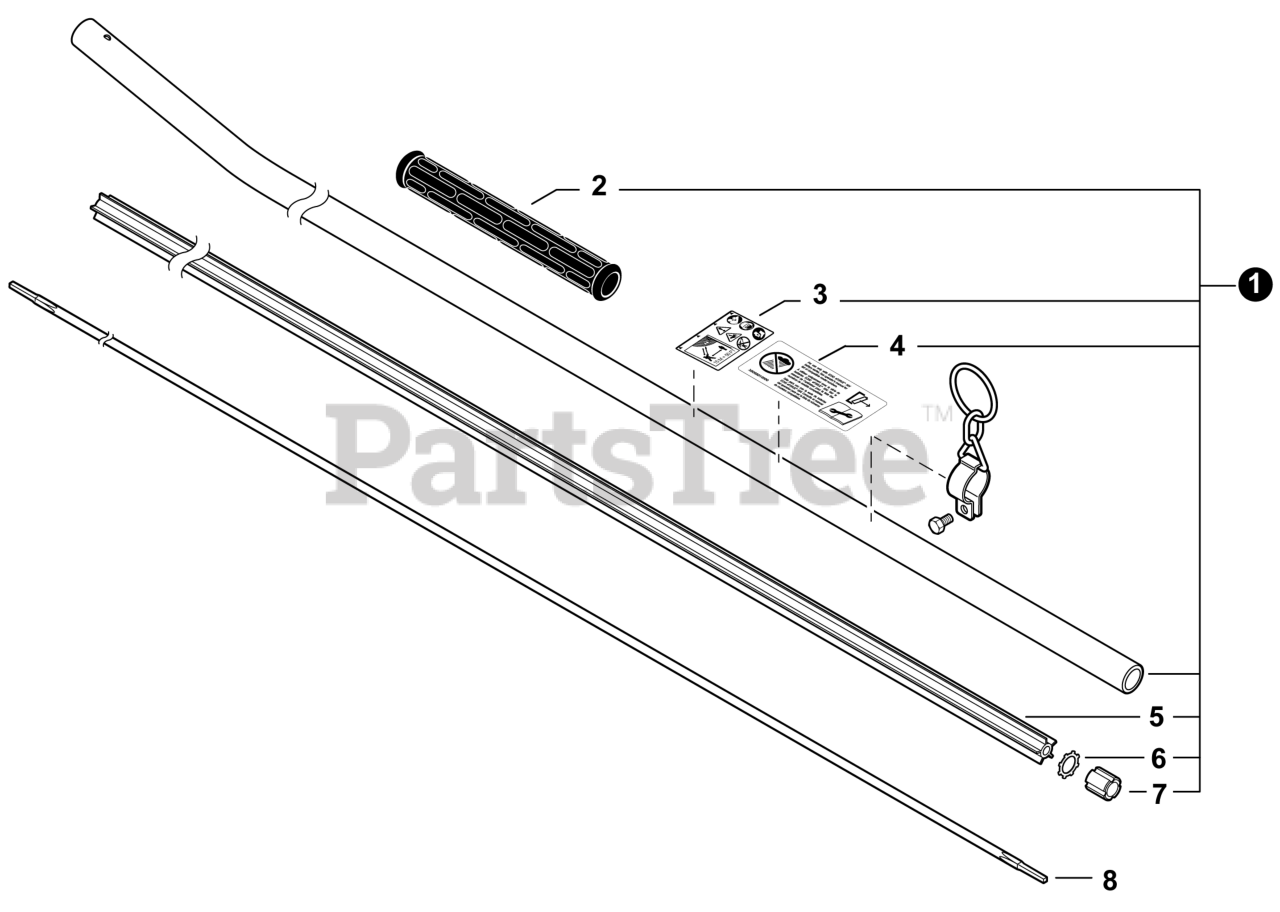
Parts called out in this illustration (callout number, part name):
1	MAIN PIPE ASSY
2	GRIP, FRONT
3	LABEL - CAUTION ISO
4	LABEL - CAUTION - UL
5	WASHER
6	LINER - FLEXIBLE
7	STOPPER
8	DRIVESHAFT - FLEXIBLE
